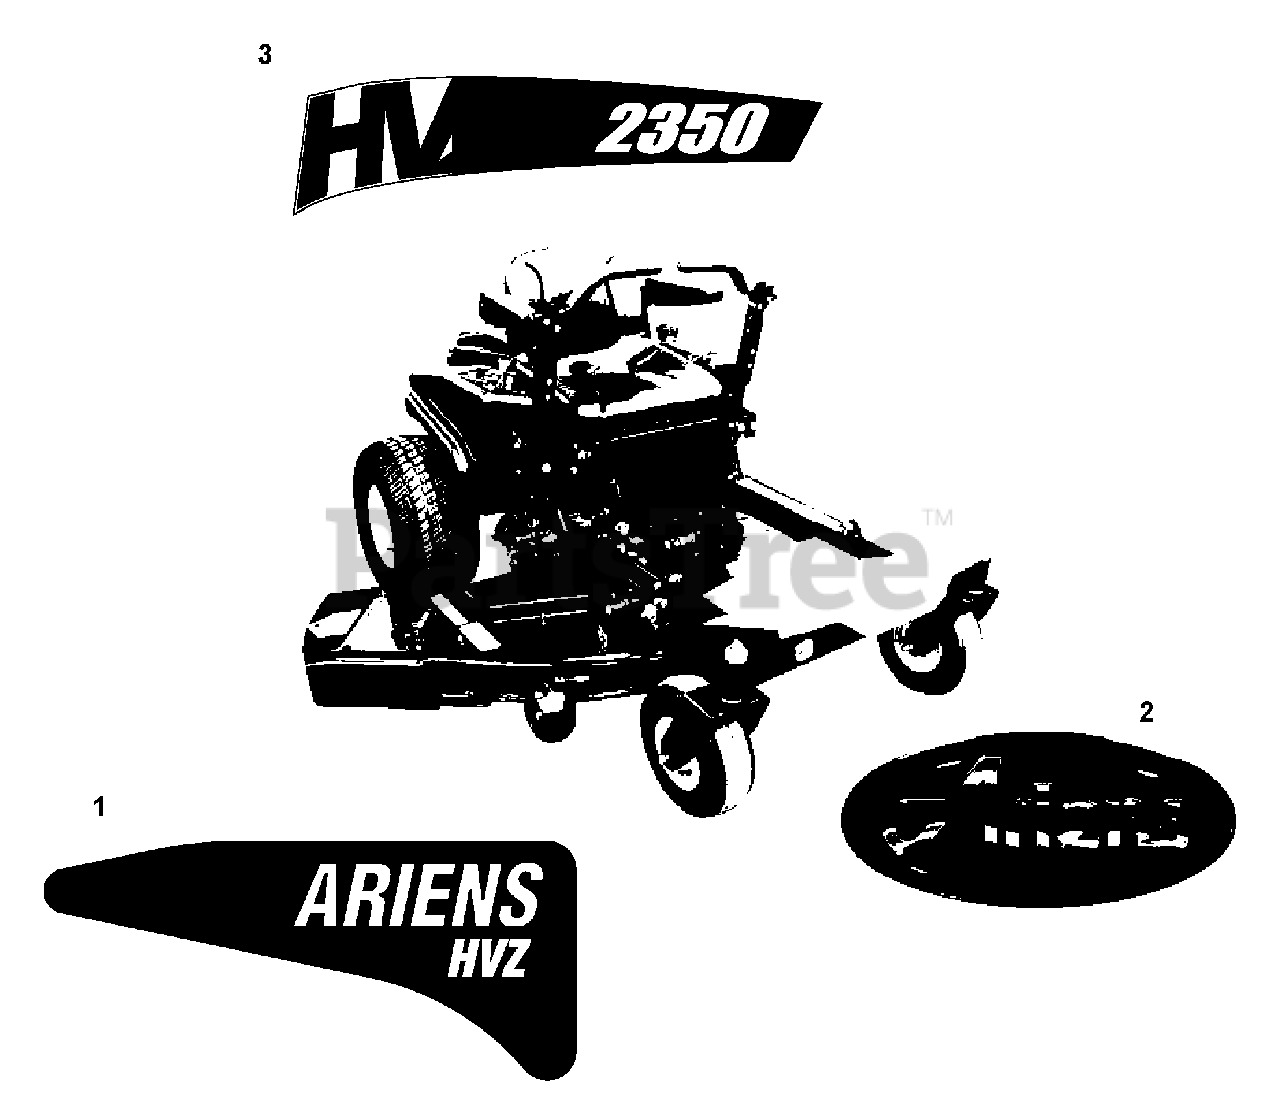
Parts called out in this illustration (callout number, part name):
1	DECAL, HVZ RH FENDER, ARIENS
2	DECAL-ARIENS JEWEL
3	DECAL HVZ 2350, ARIENS
